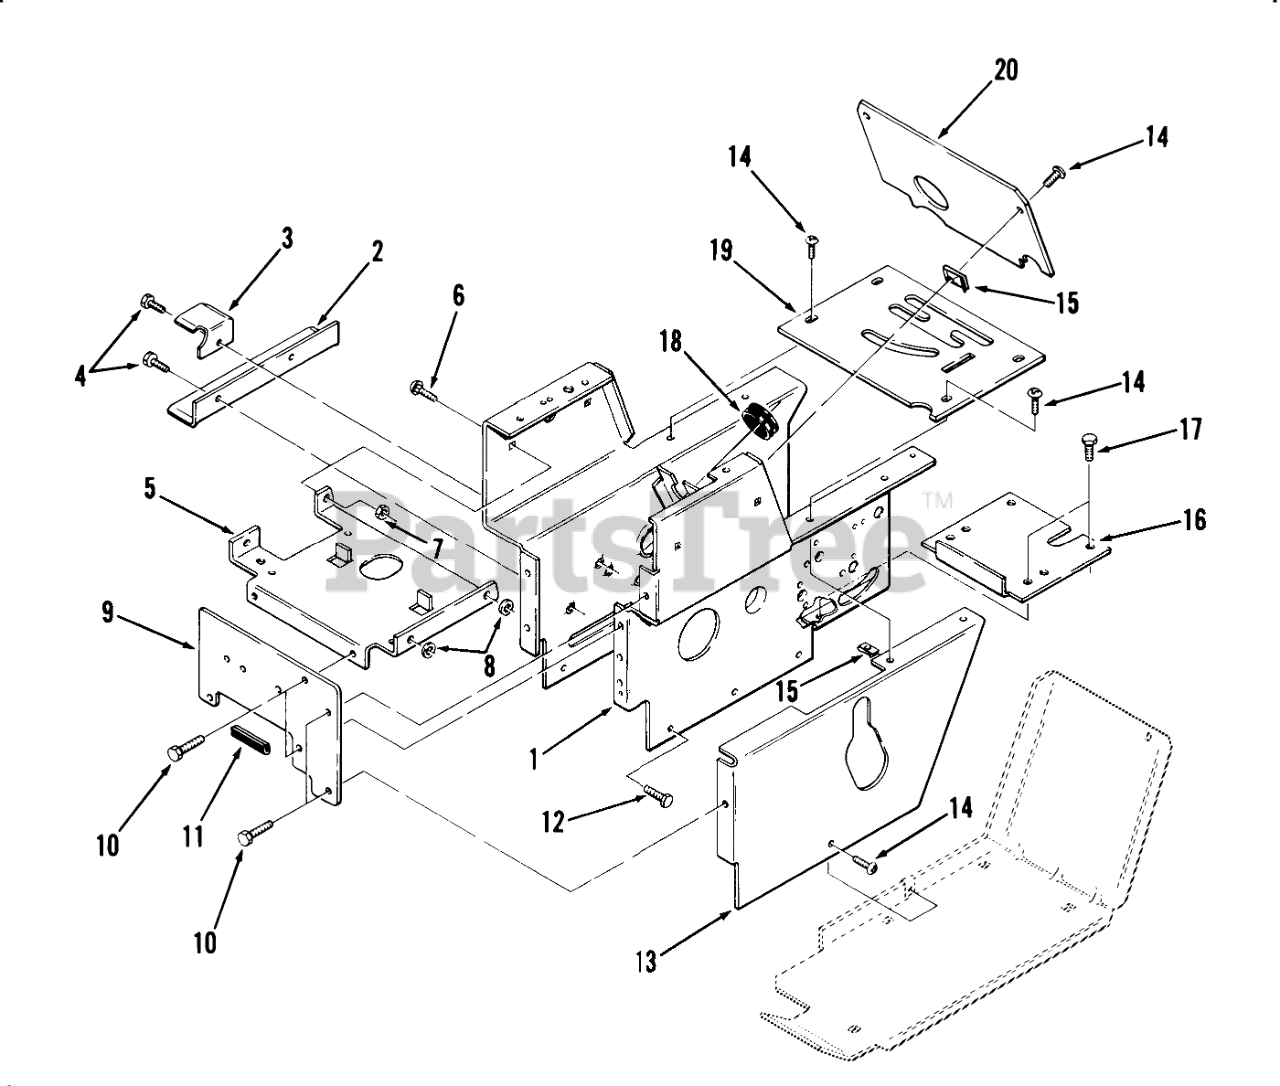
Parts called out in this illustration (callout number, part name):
2	ANGL-BLT GURD*B
4	SCREW
10	SCREW
17	SCREW
18	GROMMET
19	Shift Cover Plate
